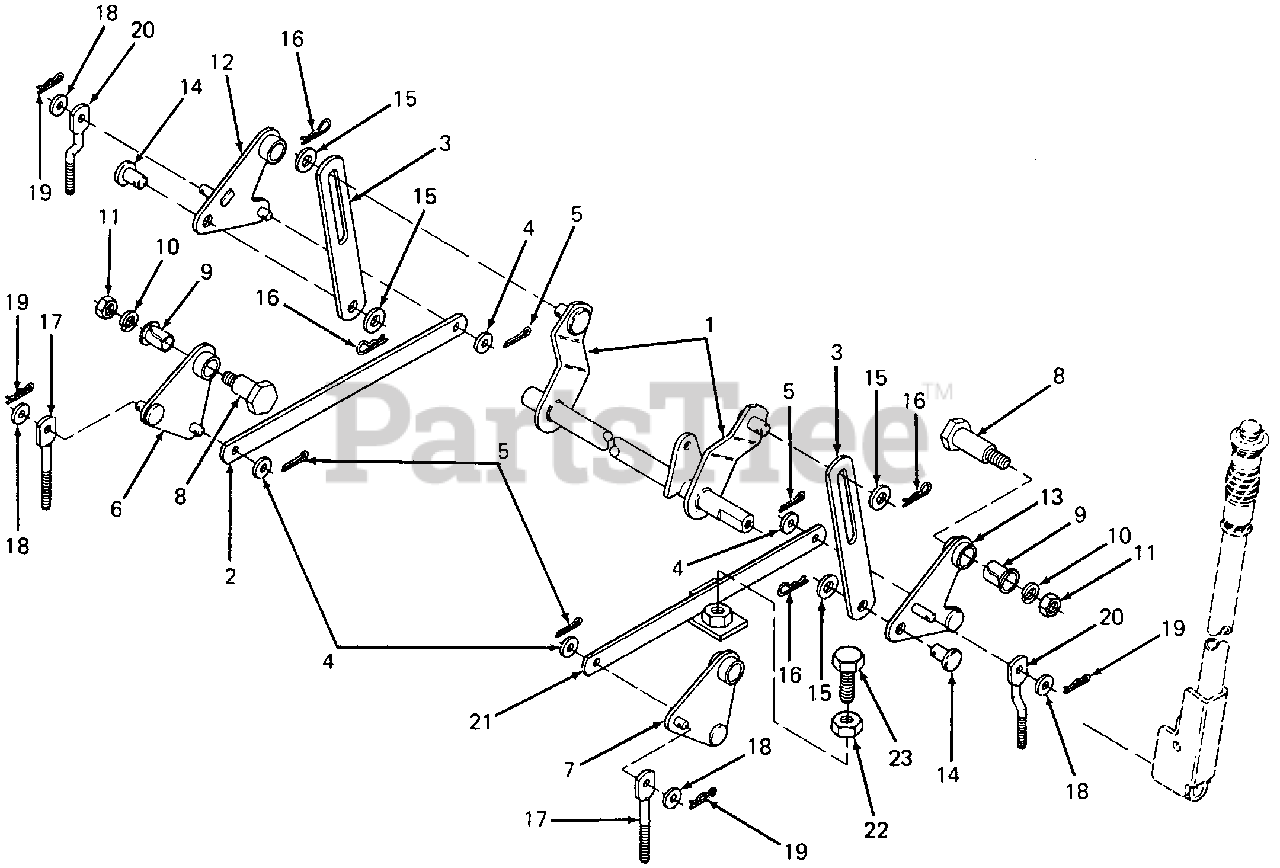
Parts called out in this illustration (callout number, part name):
1	Shaft Assy, Lift
3	Link, Lift
4	Washer, Flat, .406 X 1.0 X .030 Thk
5	Pin, Cotter, 1/8 X 3/4 Lg
6	Cam Assy, Rear Lift - LH
7	Cam Assy, Rear Lift - RH
8	Screw, Shoulder, .625 X .960
9	Bearing, Flanged Nyliner
10	Washer, Lock, 3/8
11	Nut, Hex Center Lock, 3/8-16 GR5
12	Cam Assy, Front Lift - LH
14	Pin, Clevis, .50 Dia X .62 Lg
15	Washer, Flat, .510 X 1.0 X .06 Thk
16	Pin, Internal Cotter
17	Link, Rear Lift
18	Washer, Flat, .406 X .75 X .063 Thk
19	Pin, Internal Cotter
20	Link, Front Lift
21	Lift Stop Assy
22	Nut, Hex, 3/16-18 GR5
23	Screw, Hex Cap, 3/8-16 X 1.0 Lg GR5
